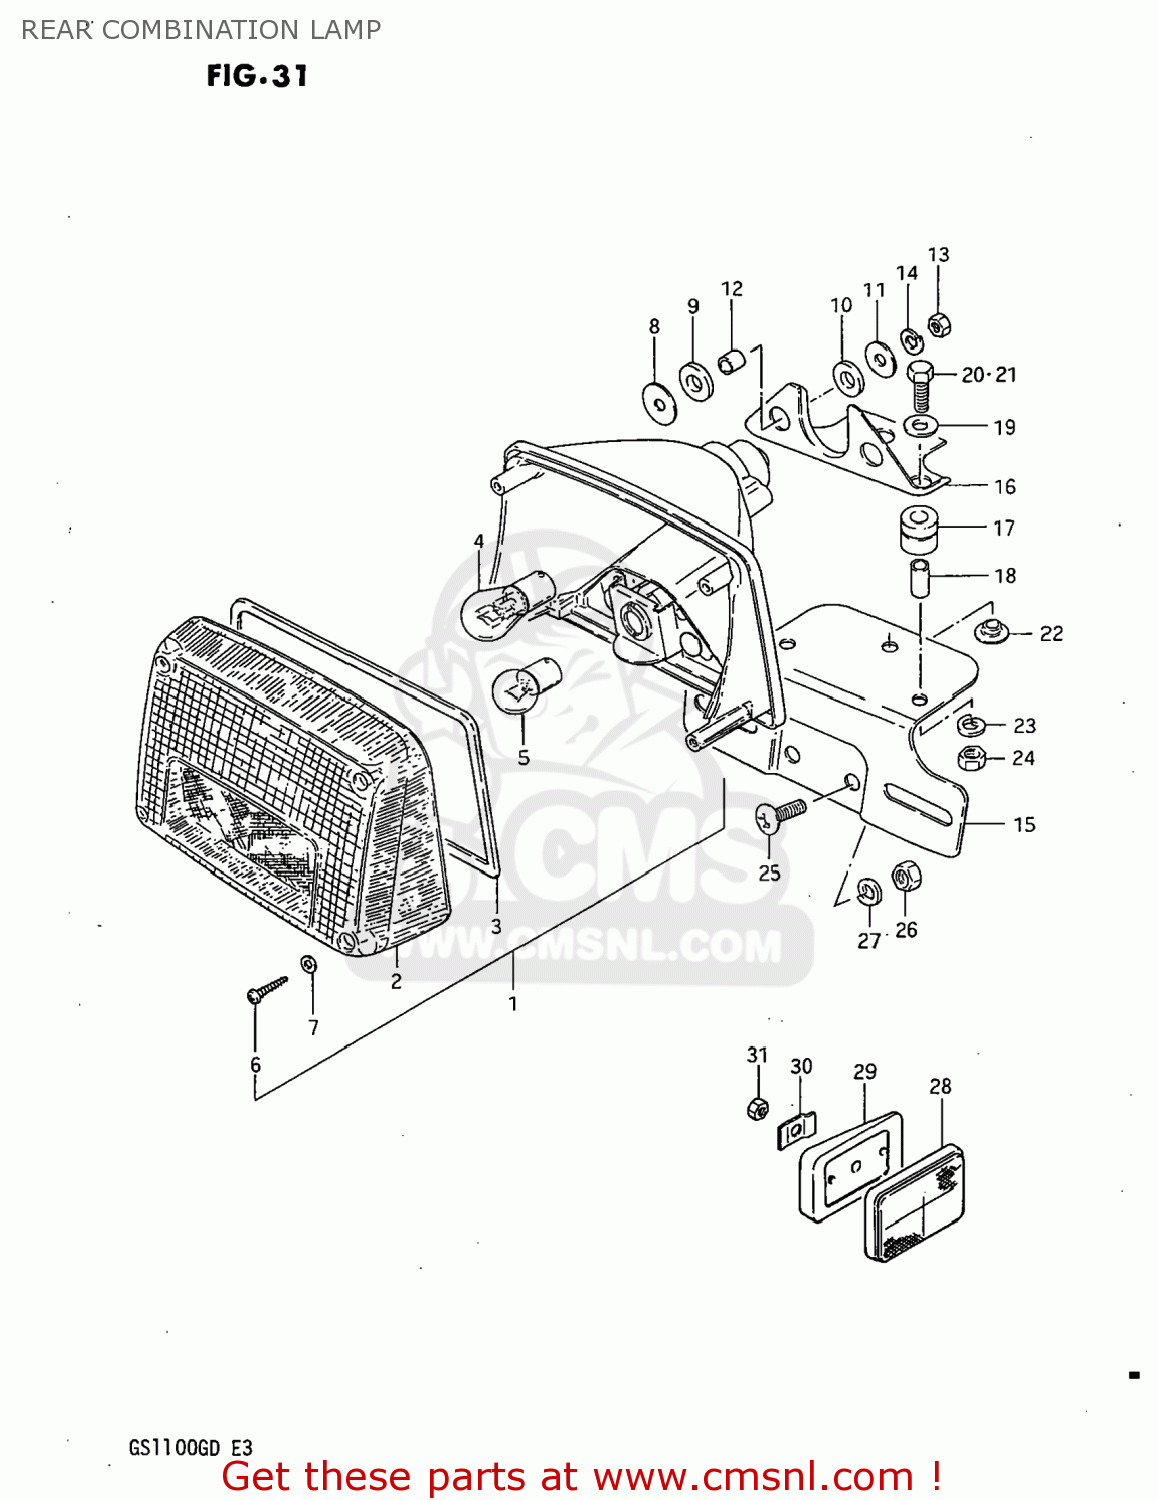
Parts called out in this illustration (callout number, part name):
1	LAMP ASSEMBLY,REAR COMBINATION
2	LENS
3	GASKET (NAS)
4	BULB(12V23W)
5	BULB
6	SCREW,REAR COMBINATION LAMP
7	GASKET (NAS)
8	WASHER
9	CUSHION
10	CUSHION
11	WASHER(6,5X22X1.6)
12	SPACER(6.1X9X7.5)
13	NUT
14	LOCK WASHER
15	PLATE,REAR LICENSE
16	BRACKET,LICENSE PLATE
17	CUSHION, BRACKET
18	SPACER (6.4X9X15.5)
19	WASHER
20	BOLT
21	BOLT
22	WASHER
23	LOCK WASHER
24	NUT
25	SCREW
26	NUT
27	LOCK WASHER
28	REFLECTOR,REFLEX
29	SPACER
30	WASHER
31	NUT
